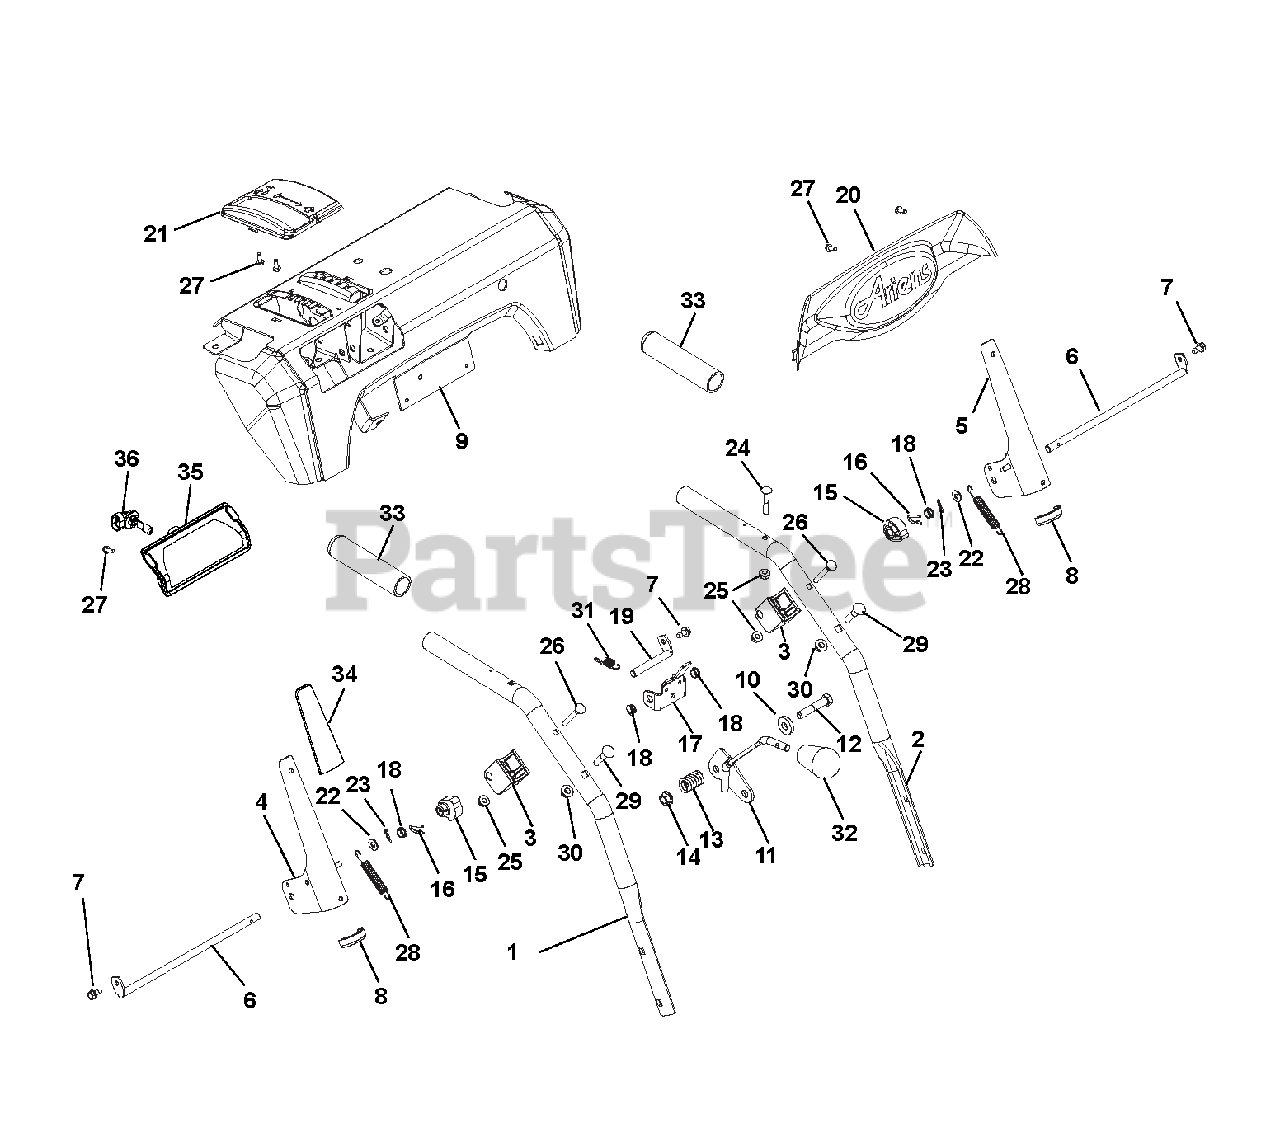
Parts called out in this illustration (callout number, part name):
1	HANDLEBAR, UPPER - RH
2	HANDLEBAR, UPPER - LH
3	BLOCK, CLUTCH PADDLE
4	LEVER, CLUTCH-RH
5	LEVER, CLUTCH-LH
6	ROD, PADDLE MOUNT - PRO
7	SCR-TAP .25-20X.50 HWH TR YWZ
8	EDGING, CLUTCH PADDLE - 2.00"
9	CONTROL PANEL W/DECAL
10	WSHR-FL-STL .406X1.00X.188 YWZ
11	WELDMENT, CONTROL LEVER(SHIFT)
12	@BLT-HEX .38-16X2.00 GR5 YWZC
13	SG-COMP .125X.781X1.250
14	@NUT-LK-TOP-FLG .38-16 YWZC
15	CAM, INTERLOCK
16	PIN, SPRING CLIP
17	BRACKET, INTERLOCK ARM
18	BUSHING, POLYLINER-.38 SNAPIN
19	ROD, PIVOT - INTERLOCK
20	DASH BEZEL, ARIENS LOGO - PRO
21	BEZEL, SHIFT ONLY
22	@WSHR-FL-STL.281X.62X.065 YWZC
23	PIN-HAIR INT .06X.18X.77
24	BLT-RDHDXLSQNK.25-20X1.25 G5ZC
25	@NUT-LK-TOP-FLG .25-20 YWZC
26	BLT-RDHDXLSQNK .25-20X2.0 G5YZ
27	SCR-TAP #10X.50 BOSS INDHXHD
28	SPRING, EXTENSION
29	@BLT-RDHDSQNK .31-18X1.50 G5YZ
30	@NUT-LK-TOP-FLG .31-18 YWZC
31	SPRING-EXT .047X.438X1.45
32	KNOB,SOFT TEARDROP,PUSH-ON GRY
33	HANDLE GRIP
34	CLUTCH PADDLE SLEEVE - GRAY
35	HEADLIGHT ASSY, HALOGEN 20W
36	BULB, LIGHT-HALOGEN 20W
